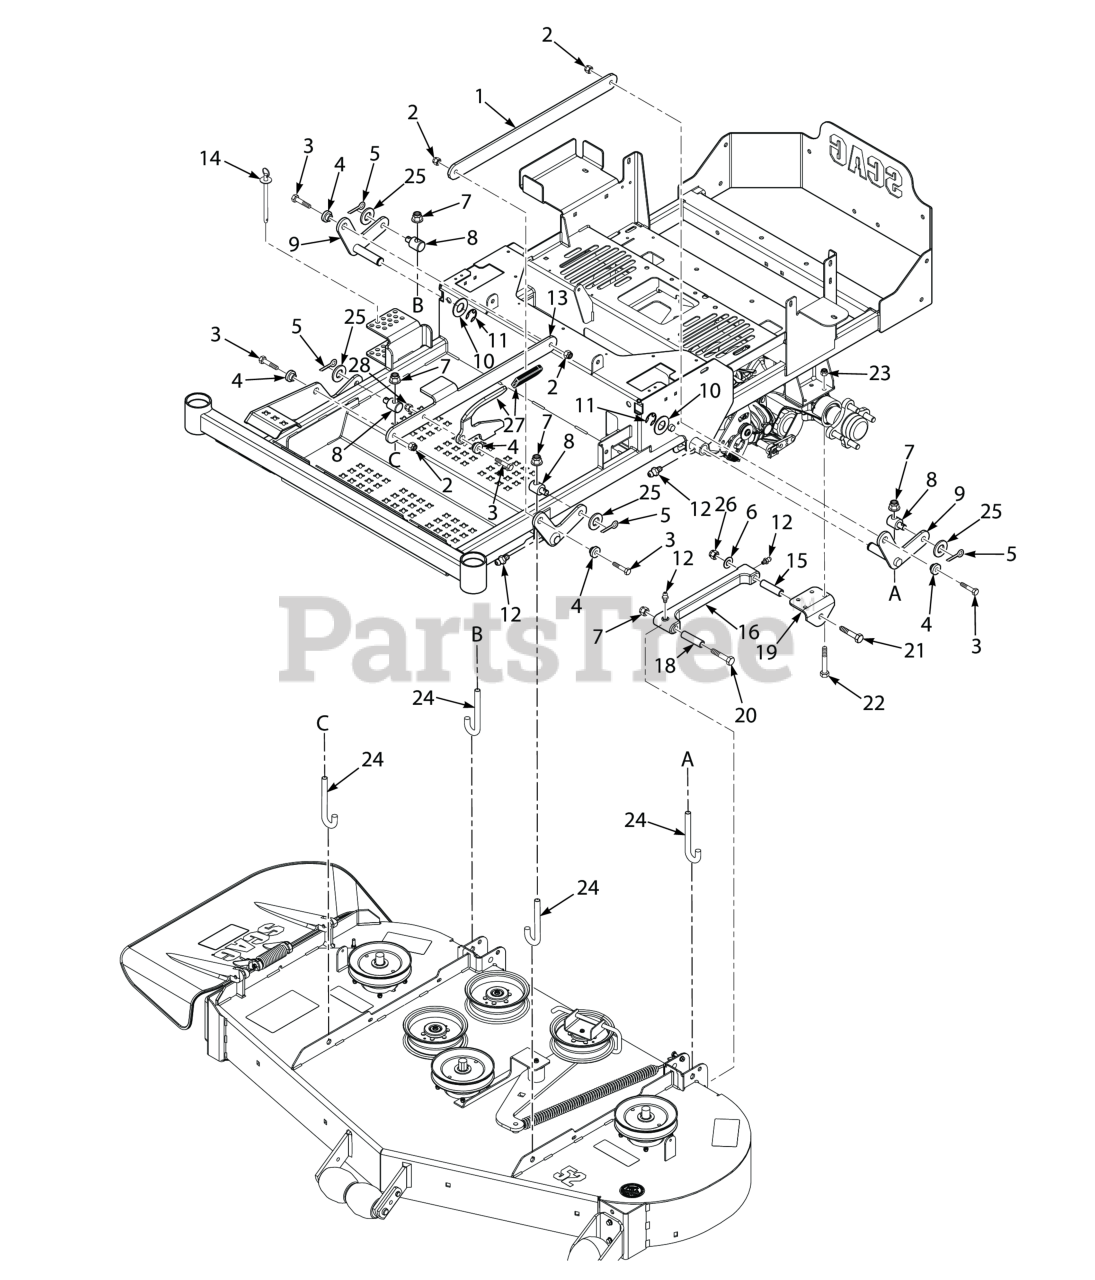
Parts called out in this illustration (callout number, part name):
1	Link, Deck Lift - LH
2	Nut, Flange Elastic Stop Nut, 3/8-16
3	Bolt, Hex Head 3/8-16 x 1-1/4", Kawasaki FX / FT & FT-EFI
4	BUSHING, SPEED ADJUSTMENT LEVER
5	Pin, Cotter 3/16 x 1.0"
6	Flatwasher, 1/2 - .531 x 1.062 x .095
7	HEX LOCKNUT, ELASTIC STOP, 1/2-13
8	Joint, Swivel
9	Lift Bellcrank Weldment
10	Flatwasher, 3/4 (.766 x 1.250 x .060)
11	RETAINING RING, 3/4" EXTERNAL "E"
12	GREASE FITTING, STR. 1/4-28 SELF TAP.
13	Link, Deck Lift - RH
14	Pin Assembly, Deck Height
15	Spacer, Pusharm - Axle
16	Pusharm Assembly, LH
17	Pusharm Assembly, RH
18	Spacer, Pusharm - Deck
19	Bracket, Push Arm Link
20	Bolt, Hex Head 1/2-13 x 3-1/2"
21	Bolt, Hex Hd. 1/2-13 x 2-1/2" (lower)
22	Bolt, Hex Head 5/16-18 x 3.00"
23	HEX NUT, ELASTIC STOP LOCK, 5/16-18
24	Rod, Deck Lift
25	Flatwasher, 5/8" (.656 x 1.312 x .095")
26	Locknut, Hex 1/2-13 Center Lock
27	Lever Assembly (incl. Grip)
28	HEX NUT, ELASTIC STOP LOCK, 3/8-16
